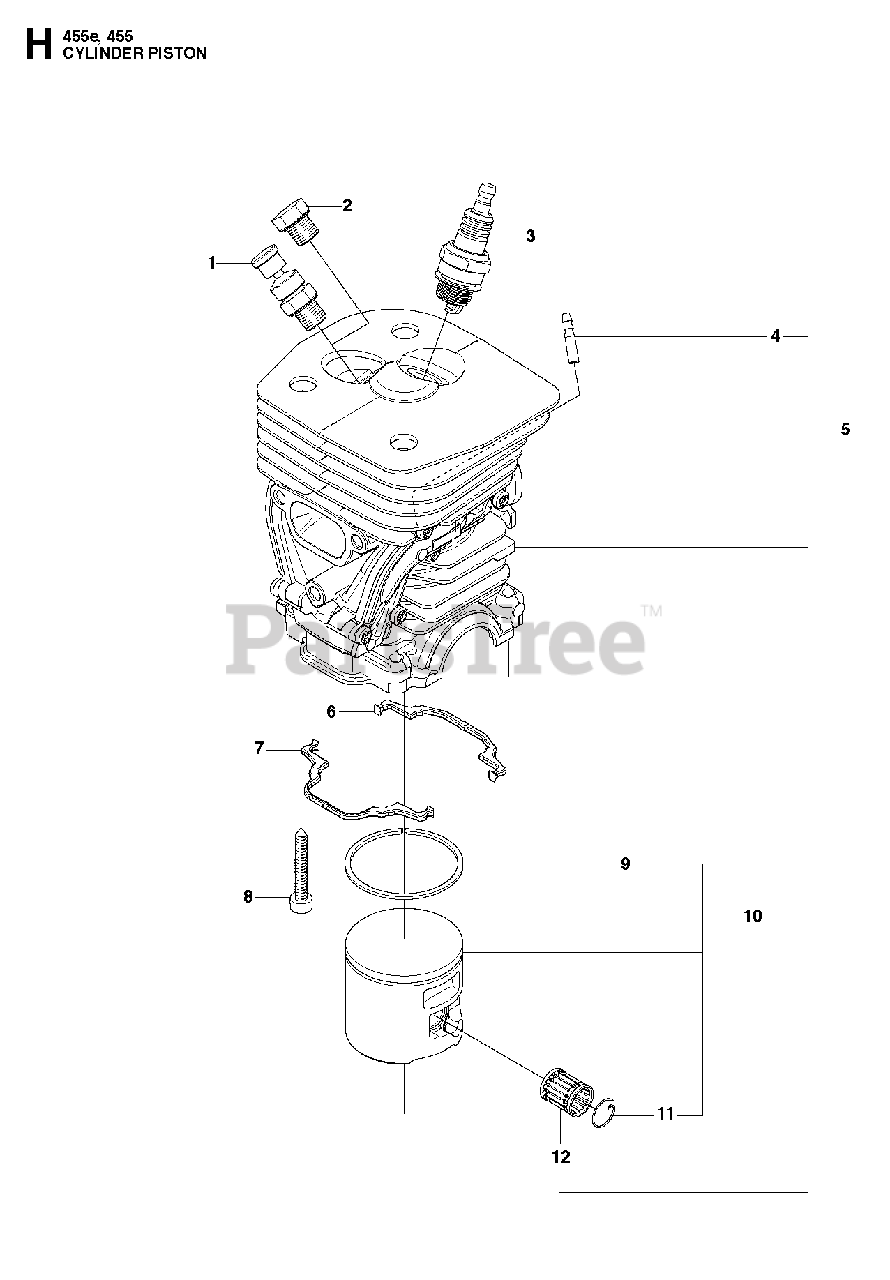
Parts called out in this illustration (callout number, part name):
1	RP VALVE
2	CYLINDER PLUG
3	SPARK PLUG RCJ7Y
4	FITTING
5	CYLINDER
9	PISTON RING
10	PISTON CPL.
11	WRIST PIN CLIP
12	SUPPORT BUSHING
